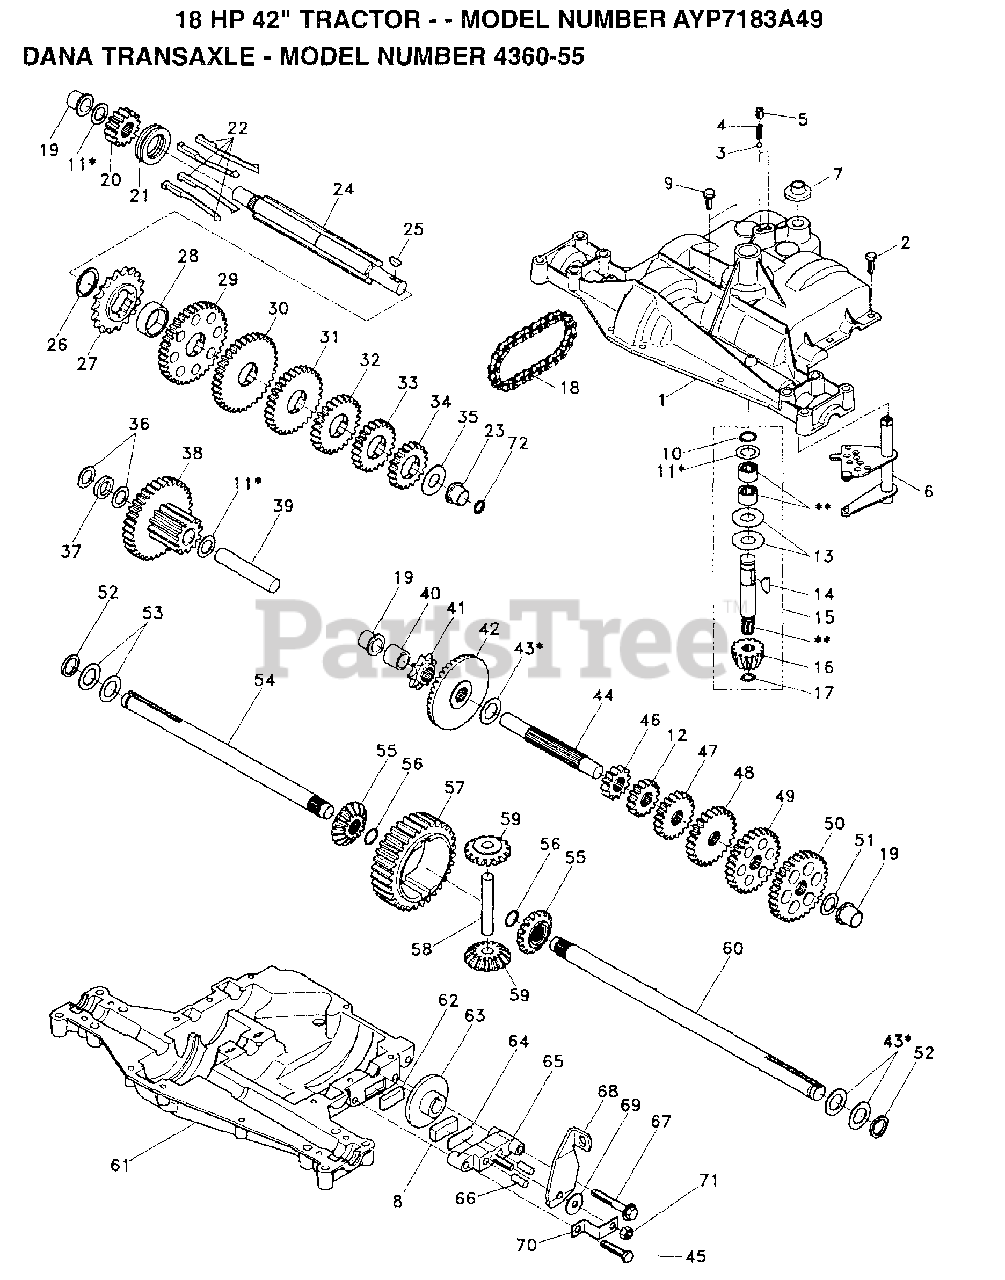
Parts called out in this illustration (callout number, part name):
1	HOUSING UPPER
3	BALL, DETENT
4	SPRING, DETENT
5	SCREW, SET
6	KIT, SHIFTER ASSEMBLY
7	BOOT, SHIFTER
8	PUCK, FRICTION
9	SCREW TAPPING WITH SEALER
10	RING RETAINING
11	ASSY, KIT, SHIM .625 SHAFT
12	GEAR SPUR, 15 TEETH
13	WASHER, PLAIN .632 X 1.38 X .046
14	KEY WOODRUFF #9
15	ASSY KIT INPUT SHAFT
16	PINION BEVEL 14 TEETH
17	RING, RETAINING
18	CHAIN, 24 PITCHES
19	BEARING, FLANGE
21	COLLAR, CLUTCH
22	ASSY KIT CLUTCH KEYS
23	BEARING FL
24	SHAFT INTERMEDIATE
25	KEY, WOODRUFF, #61
26	RING, RETAINING
27	SPROCKET, 18 TEETH
29	GEAR, SPUR, 37 TEETH
30	GEAR, SPUR, 35 TEETH
31	GEAR, SPUR, 30 TEETH
32	GEAR, SPUR, 25 TEETH
33	GEAR, SPUR, 22 TEETH
34	GEAR, SPUR, 19 TEETH
35	WASHER, PLAIN .640 X 1.37 X .061
36	WASHER, PLAIN .632 X 1.00 X .026
37	SPACER .630 X 1.00 X .169
38	ASSY GEAR COMB 12&35 TEETH
39	SHAFT, IDLER
40	SPACER .635 X .875 X .755
41	SPROCKET, 9 TEETH
42	GEAR, BEVEL, 42 TEETH
43	ASSY, KIT, SHIM .750 SHAFT
44	SHAFT, DRIVE
45	SCREW TAPPING
46	GEAR, SPUR, 12 TEETH
47	GEAR, SPUR, 20 TEETH
48	GEAR, SPUR, 25 TEETH
49	GEAR, SPUR, 28 TEETH
50	GEAR, SPUR, 31 TEETH
51	WASHER, PLAIN .632 X 1.00 X .060
52	WASHER, NEOPRENE
53	WASHER, PLAIN .758 X 1.25 X .031
54	AXLE LEFT HAND
55	GEAR MITER 15 TEETH
56	RING, RETAINING
57	GEAR, SPUR, 32 TEETH
58	SHAFT, CROSS
59	GEAR, MITER, 15 TEETH
60	AXLE, R.H.
61	HOUSING LOWER
62	PUCK, FRICTION
63	DISC, BRAKE
65	JAW, BRAKE
66	PIN, DOWEL
67	SCREW, SELF-TAPPING
68	LEVER ACTUATING
69	WASHER, PLAIN .321 X 1.00 X .055
70	BRACKET, ANTI-ROTATION
71	LOCKNUT 5/16-24
72	SQUARE RING
